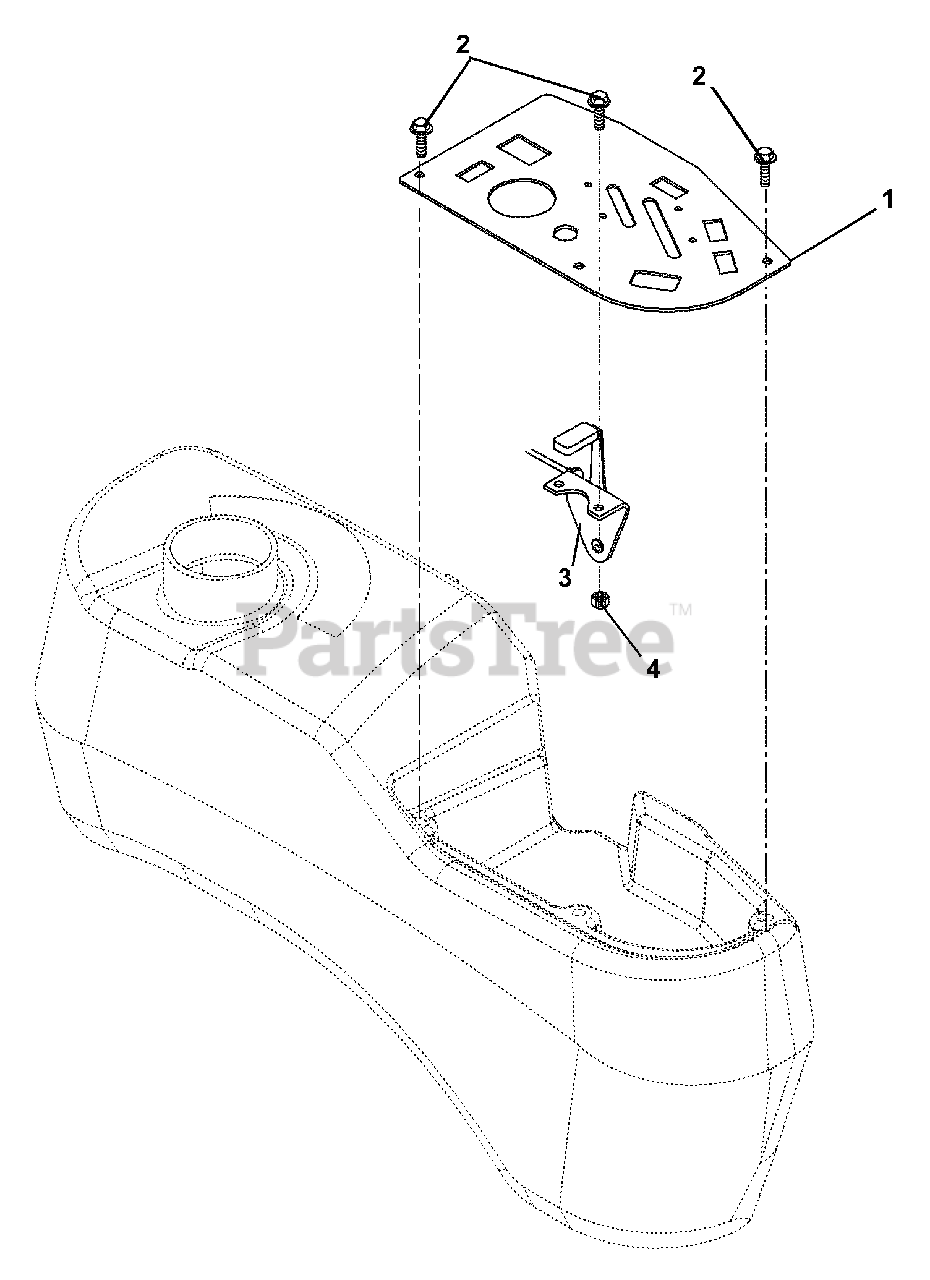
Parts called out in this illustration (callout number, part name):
1	PANEL, L/C CONTROL - BLACK
2	@SCR-MCH 10-24X.50 HWH YWZC
3	THROTTLE, CONTROL (DIESEL)
4	@NUT-LK-NYL 10-24 W/INSRT YWZC
